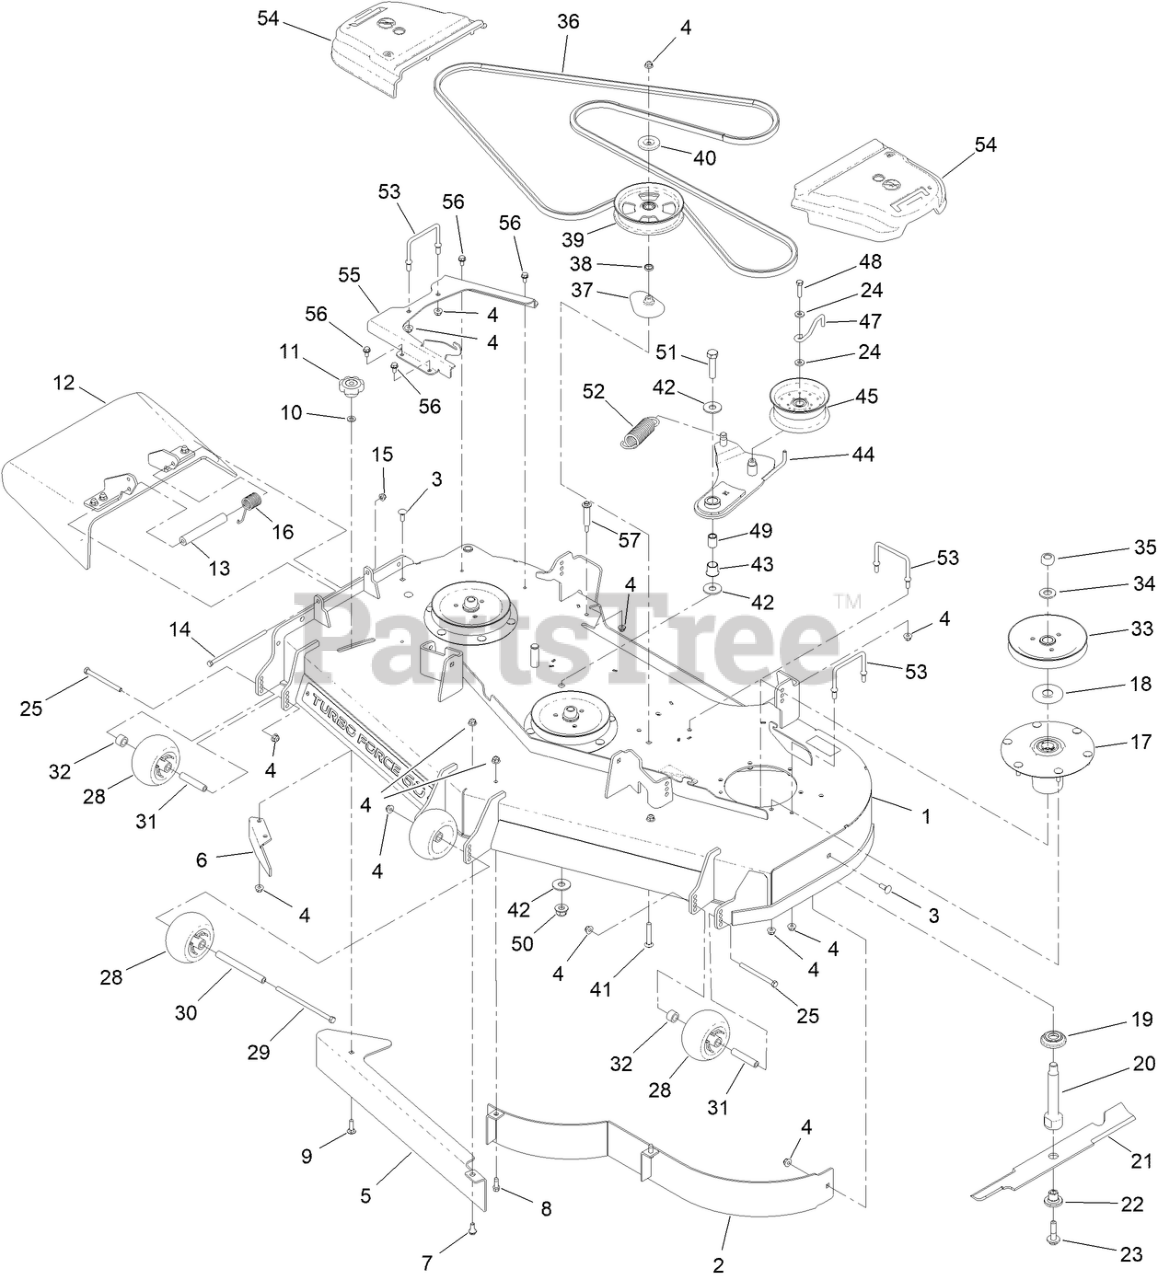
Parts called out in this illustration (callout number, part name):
1	60 DECK ASM W/DECALS
2	BAFFLE ASM
3	BOLT-CARR
4	NUT-HF, NI
5	PLATE-BAFFLE, FORMED [RED]
6	BAFFLE-DISCHARGE
7	BOLT-SHOULDER
9	BOLT-CARR
10	WASHER-HARDENED
12	RUBBER DEFLECTOR ASM
13	SPACER
14	SCREW-HH
15	NUT-HF, NI
16	SPRING-TORSION
17	SPINDLE ASM
18	GUARD-BEARING, TOP
19	GUARD-BOTTOM
20	SHAFT-SPINDLE
22	BUSHING-HEX
23	SCREW-SEMS
24	SPACER-HUB, BLOWER
25	SCREW-HH
28	ROLLER-SCALP, ANTI
29	SCREW-HH
30	SPACER-WHEEL
31	TUBE-SHAFTING
32	TUBE-SPACER
33	SHEAVE-DRIVE, BLADE
34	WASHER
35	NUT-HEX
36	BELT-V
37	SPACER-PULLEY
38	SPACER-PLATE, BBC
39	PULLEY-IDLER, FLAT
40	SHIELD-DUST
41	SCREW-CARR
42	WASHER-FLAT
43	BUSHING, IGUS
44	IDLER ARM ASM [BLACK]
45	IDLER-PULLEY, FLAT
47	WIREFORM BELT GUIDE,IDLER, TOP
48	SCREW-HH
49	BUSHING-IDLER PIVOT
50	NUT-HF
51	SCREW-HH
52	SPRING-EXTENSION
53	WIREFORM-COVER
54	COVER-BELT, LH
55	PLATFORM, BELT COVER 60
56	SCREW-HWHTF
57	BOLT-SHOULDER
